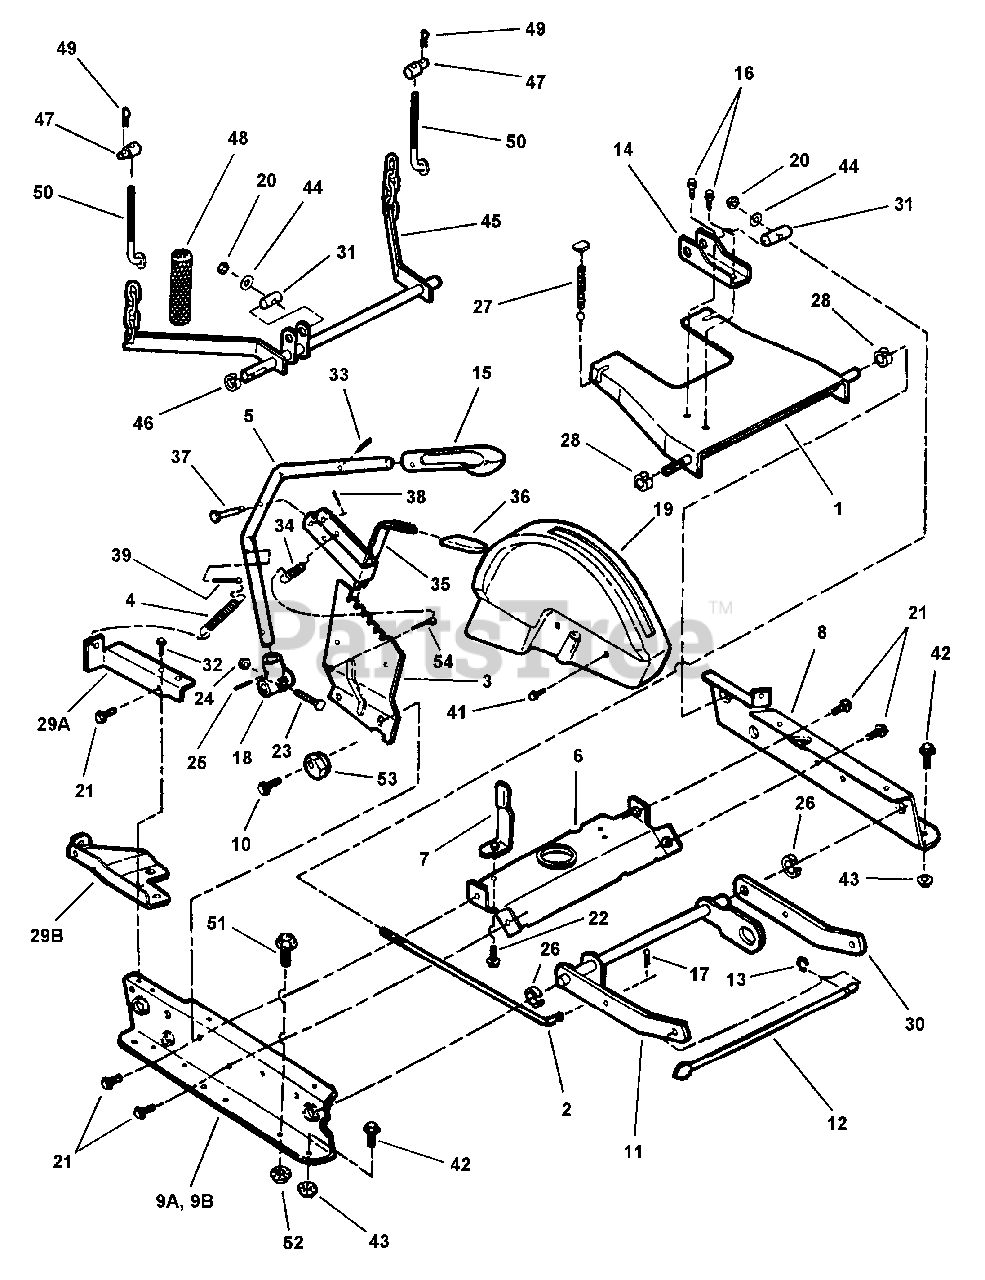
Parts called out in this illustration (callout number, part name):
1	ARM, Rear Lift
2	ROD, Leveling
3	QUADRANT, Lift Lever
4	SPRING, Extension
5	LEVER, Lift
6	BRACE, Top
7	GUIDE, Belt
8	RAIL, Left Hand
9A	RAIL, R.H.
9B	RAIL, R.H.
10	SCREW, 3/8-16 x 1" Hex Washer Self-Tap
11	ARM, Front Lift, Adjustable
12	ROD, Support (Front Lift Arm to Front End)
13	SNAP RING, 7/16" External
14	ARM, Leveling
15	GRIP, Height Adjustment Lever
16	SCREW, 5/16-18 x 5/8" Truss Head Self-Tap (Torx)
17	PIN, 1/8 x 3/4" Cotter
18	HUB, Deck Lift
19	COVER, Height of Cut
20	NUT, 3/8-24 Hex Nyloc
21	SCREW, 3/8-16 x Hex Washer Self-Tap
22	SCREW, 5/16-18 x 5/8" Hex Washer Self-Tap
23	BOLT, 5/16-24 x 1-5/8" Tapered Axle
24	NUT, 5/16-24 Hex Flange Lock
25	PIN, 3/16 x 1" Roll
26	RING, Red
27	CABLE, Rear Deck
28	RING, White
29A	BRACKET, Deck Lift
29B	BRACKET, Lift Assist
30	ARM, Front Lift-Left
31	PIVOT, Leveling
32	SCREW, 1/4-20 x 3/4" Hex Washer Self-Tap
33	PIN, 3/16 x 3/4" Roll
34	SPRING, Latch
35	LATCH
36	GRIP, Lift Latch
37	PIN, 1/4 x 1-1/4" Clevis
38	COTTER-PIN, 1/16 x 3/4"
39	COTTER-PIN, 3/16 x 1-1/2"
41	SCREW, 1/4-20 x 5/8" Hex Washer Self-Tap
42	BOLT, 5/16-18 x 5/8" Hex Flange Lock
43	NUT, 5/16-18 Hex Flange Lock
44	WASHER, 3/8" Flat
45	ARM, Rear Lift
46	RING, Blue
47	SWIVEL
48	COVER, Chain
49	HAIRPIN, 3/32 x 1-1/2"
50	HOOK, Chain
51	BOLT, 1/4-20 x 1/2" Hex Flange Lock
52	NUT, 1/4-20 Hex Flange Lock
53	ECCENTRIC
54	COTTER-PIN, 3/16 x 3/4"
